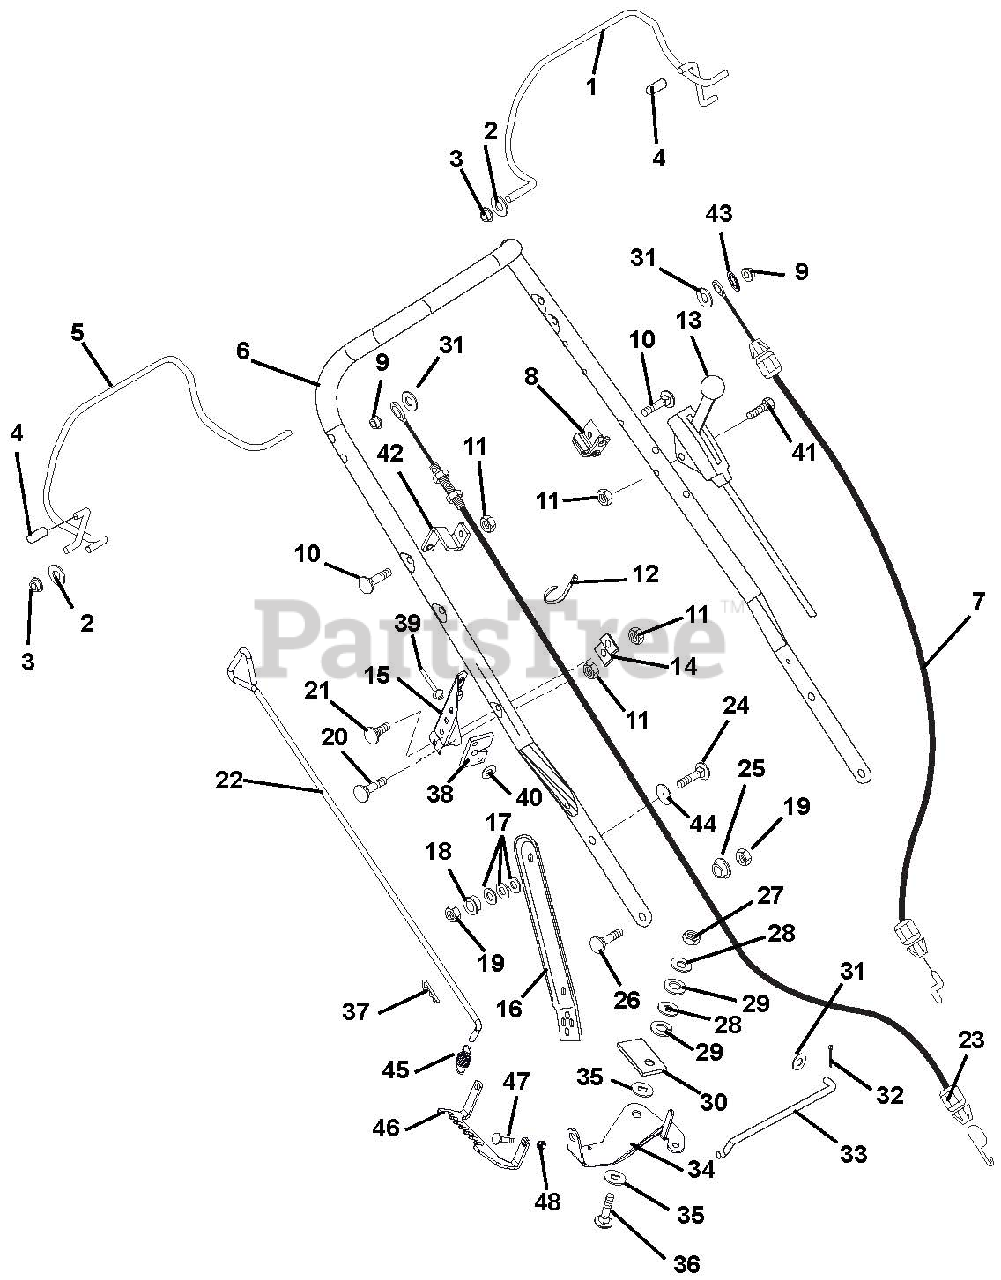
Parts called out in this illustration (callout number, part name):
1	BAIL, WBLM ENGINE
2	@WSHR-FL-STL.344X.688X.065YWZC
3	BSHG-FLG .325X.444X.440X.560
4	CAP, VINYL, .25 ID
5	BAIL, WBLM TRACTION
6	HANDLE BAR, CLASSIC LM21
7	CABLE, WBLM ENGINE
7	CABLE, ENGINE - ADJUSTABLE
8	BRKT, ENGINE CABLE ANCHOR
9	PUSH NUT, .25
10	BLT-RDHDXLSQNK.25-20X1.25 G5ZC
11	@NUT-LK-CTR .25-20 YWZC
12	@NUT-LK-CTR .25-20 YWZC
12	CABLE TIE LG 5-1/2
13	CABLE, LOCKOUT CONTROL
14	BRACE, SPEED CONTROL
15	BRKT, SPD CONTROL SLOTTED
16	LINK, HANDLEBAR ADJUSTMENT LH
16	LINK, HANDLEBAR ADJUSTMENT RH
17	WASHER, BELLEVILLE YWZC
18	BSHG-FLG .325X.500X.513X.875
19	@NUT-LK-CTR .31-18 YWZC
20	BLT-RDHDSQNK .25-20X1.38 GR5YZ
21	@BLT-RDHDSQNK .25-20X.50 G5YZ
22	SPEED CONTROL ROD
23	CABLE, WBLM TRACTION
24	@BLT-RDHDSQNK .31-18X1.00 G5YZ
25	BSHG, FLG .325X.499X.26X.88
26	@BLT-RDHDSQNK .31-18X.75 G5YZ
27	@NUT-LK-CTR .38-16 YWZC
28	@WSHR-FL-STL.406X.812X.065 YWZ
29	WSHR-LK .375X.115 HVY YWZC
30	PRESSURE FLANGE
31	@WSHR-FL-STL.281X.62X.065 YWZC
32	@PIN-CTR .06X.50 EXTPRSQCT YWZ
33	SHIFT LINK
34	CRANK, SPEED CONTROL BELL
35	FRICTION WASHER
36	@BLT-RHDSSQNK .38-16X1.25 G5YZ
37	PIN-HAIR INT .08X.18X1.18 YWZC
38	PAD, RUBBER SUPPORT
39	RVT .187X.575 DOME AL BLACK
40	@WSHR-FL-STL.219X.50X.049 YWZC
41	BLT-RDHDXLSQNK .25-20X2.0 G5YZ
42	BRKT, TRACTION CABLE ANCHOR
43	RG-RTNG-EXT .250X.010
44	WSHR-FL-STL .505X.880X.072 YWZ
45	SPRING, EXTENSION
46	BRKT, SPD SELECTION
47	@BLT-RDHDSQNK .25-20X.50 G5YZ
48	@NUT-LK-CTR .25-20 YWZC
